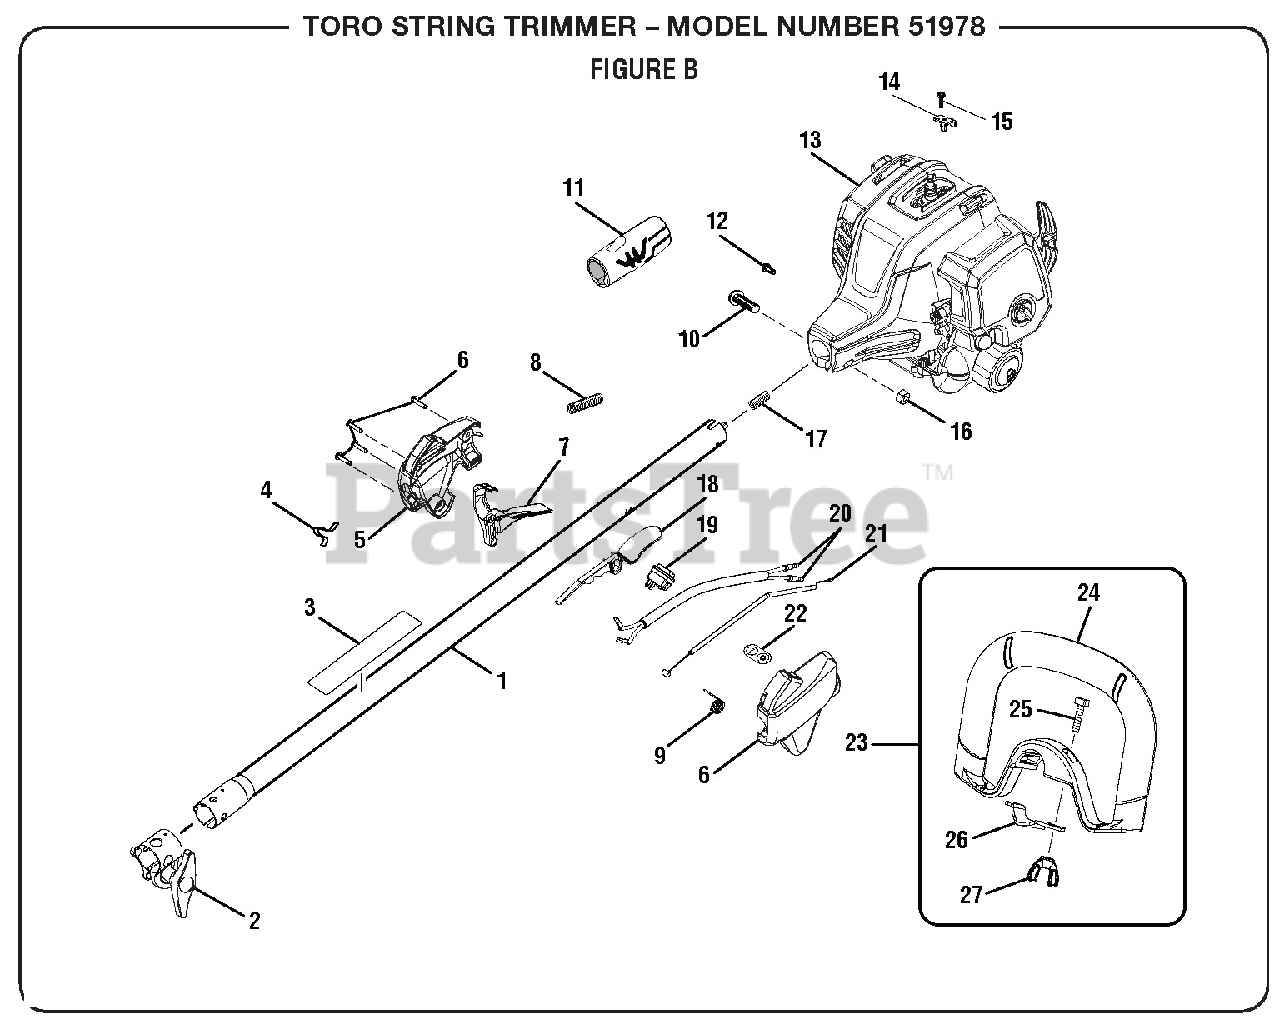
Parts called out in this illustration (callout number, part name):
1	Upper Boom Assembly
2	Boom Clamp Assembly
3	Warning Label
4	Shoulder Strap Clip
5	Control Handle Assembly
6	Screw (M4 x 20 mm, T20 Torx Hd.)
8	Corrugated Tube
9	Throttle Cable Spring
10	Screw (M6 x 30 mm)
11	Rear Handle Grip
12	Screw (M4 x 8 mm, T20 Torx Hd.)
13	Powerhead Assembly
14	Throttle Cable Clamp
15	Screw (M4 x 16 mm)
16	Hex Nut (M6.3 x 1)
17	Compression Spring
18	Trigger Lock
19	On/Stop Switch
20	Lead Assembly
21	Throttle Cable
22	On/Stop Label
23	Front Handle Assembly
24	Front Handle w/Grip
25	Screw (1/4-20 x 1 in., Sq. Hd.)
26	Front Handle Clamp
27	Wing Nut (1/4-20)
